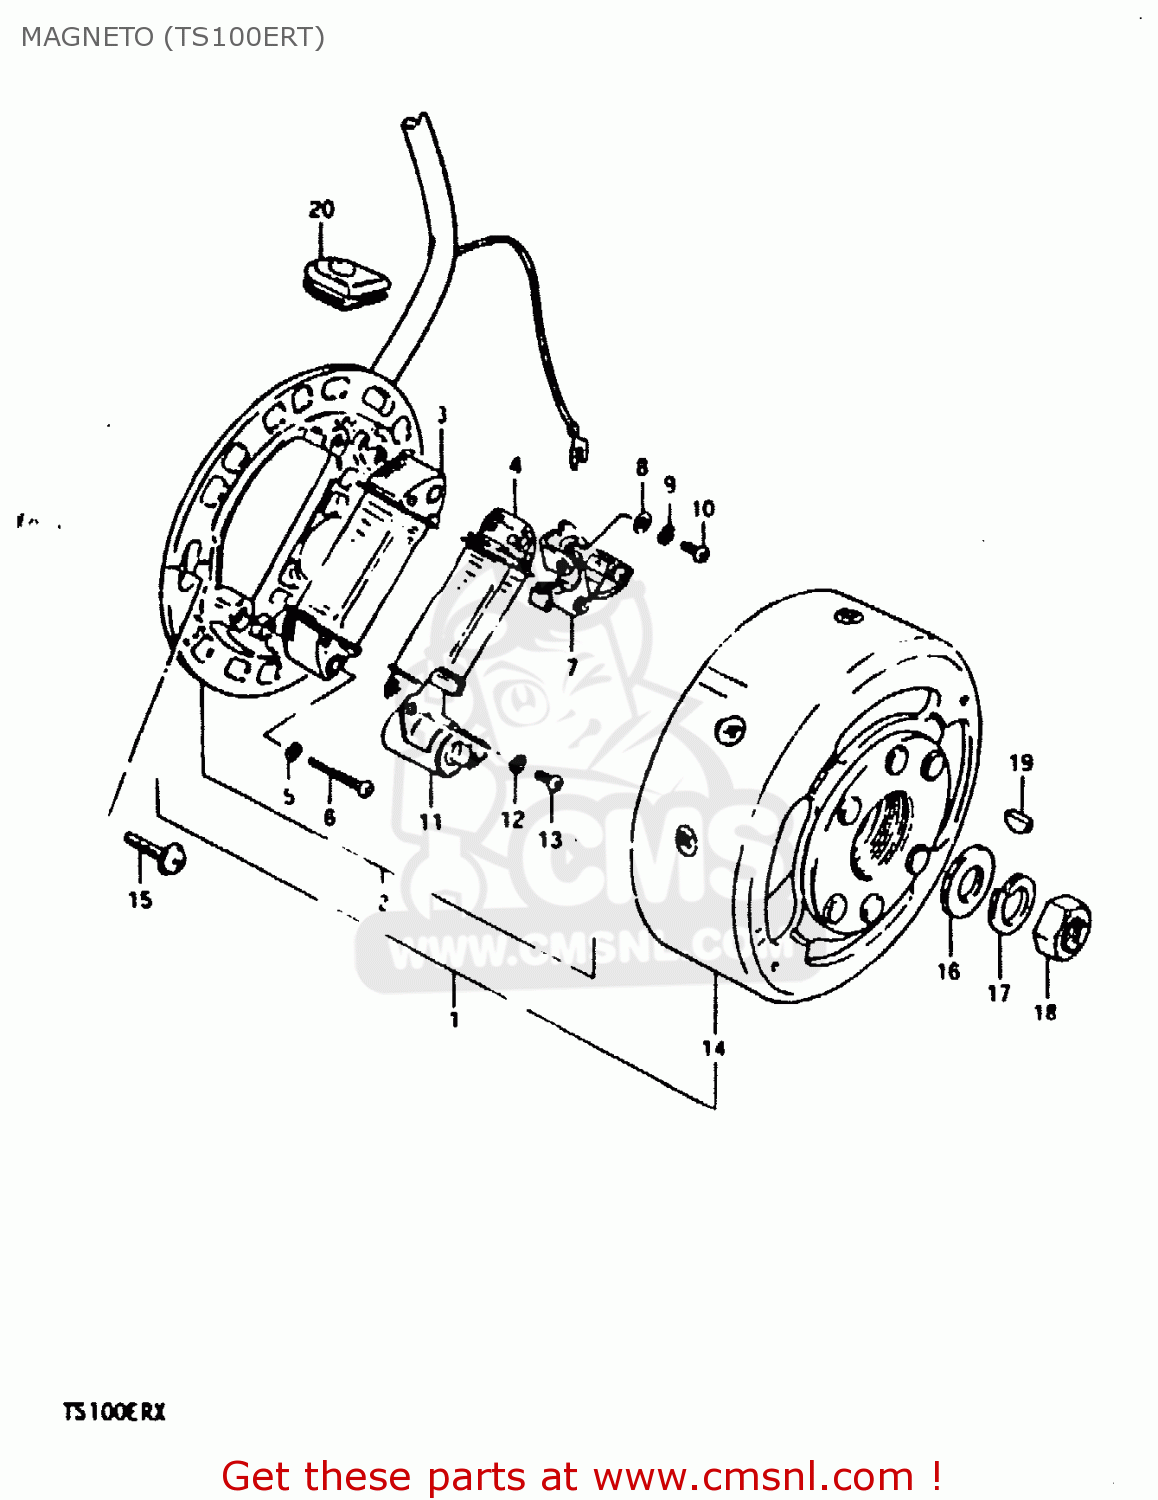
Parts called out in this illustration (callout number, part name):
1	MAGNETO ASSY
2	STARTER ASSY
3	COIL,LIGHTING
4	COIL,PRIMARY
5	LOCK WASHER
6	SCREW (4X30)
7	POINT ASSY,CONTACT
8	WASHER
9	LOCK WASHER
10	SCREW(4X10)
11	CONDENSER
12	LOCK WASHER
13	SCREW
14	ROTOR
15	SCREW(5X14)
16	WASHER
17	LOCK WASHER
18	NUT (10MM)
19	KEY
20	GROMMET
